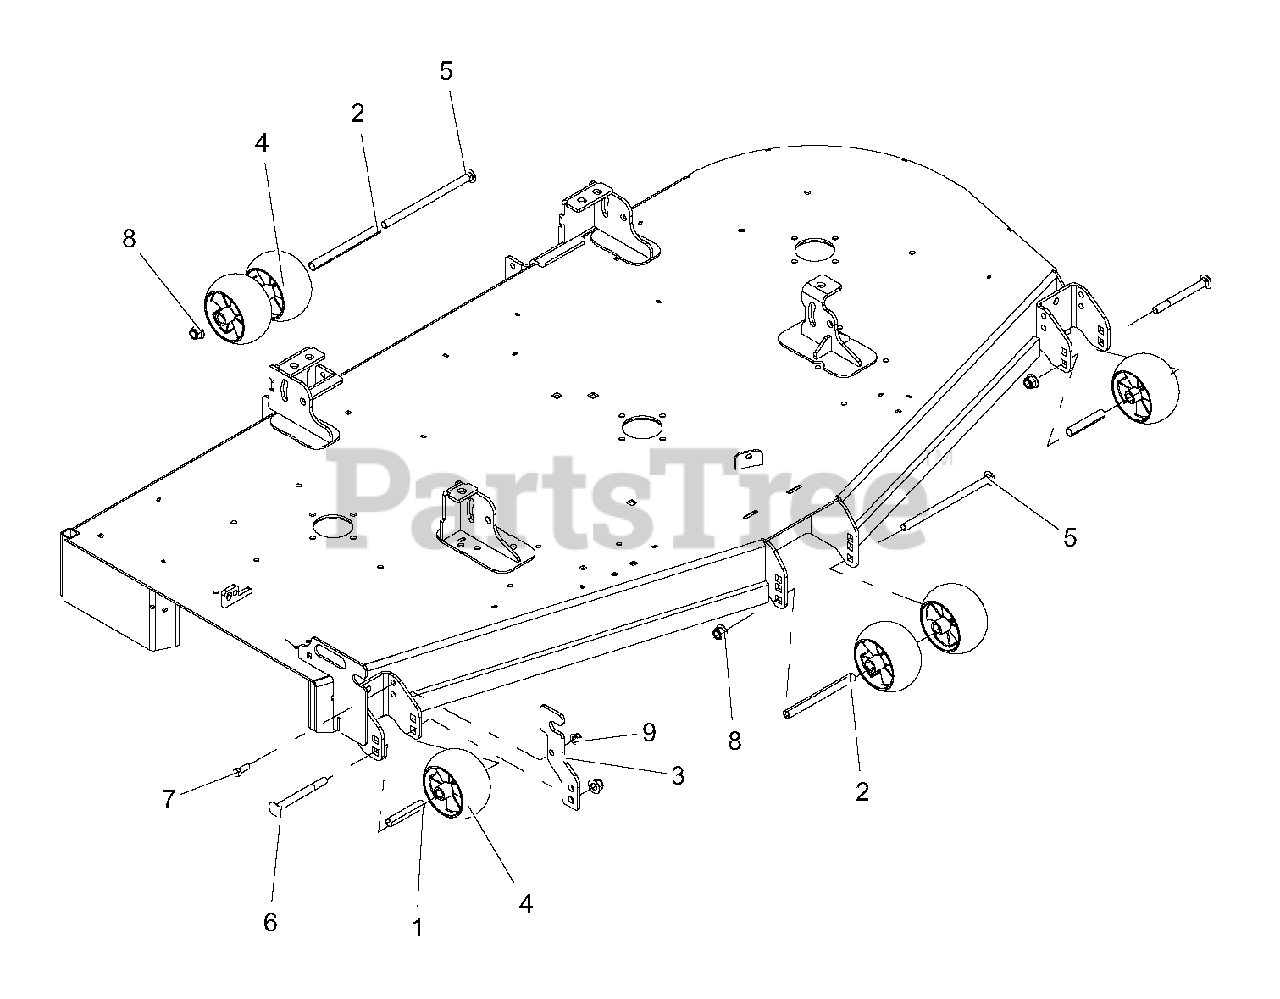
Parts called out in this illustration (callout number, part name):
1	SPACER, .510X.625X3.35
2	SPACER, .510X.625X6.70
3	CHUTE STORAGE BRACKET-RED
4	ANTI-SCALP WHEEL - 5X3 CTR
5	@BLT-RDHDSQNK .50-13X8.50 Y
6	BLT-RDHDSQNK .50-13X5.00 G5
7	BLT-HEX .38-16X1.00 GR5 YWZC
8	NUT-LK-NYL-FLG .50-13 YWZC
9	NUT-LK-NYL-FLG .38-16 YWZC
